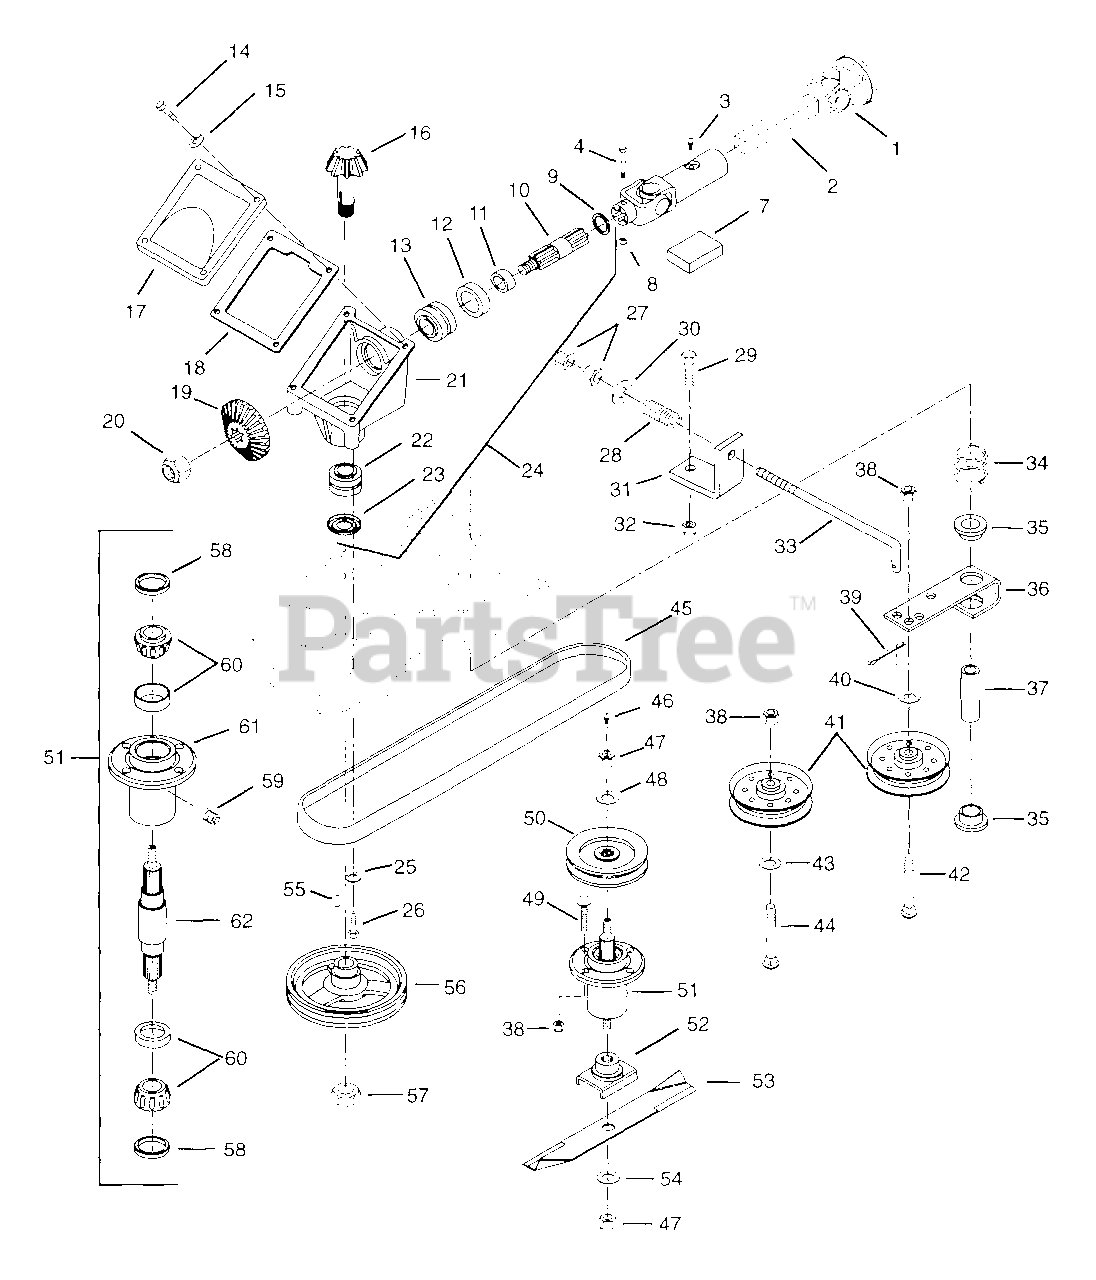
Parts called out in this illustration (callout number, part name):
1	Yoke, Quick Disconnect
2	Shaft, Prop Square Bar
3	Fitting-Lube .25-28 x .256
4	Bolt-Hex .25-20 x 2.00 Grade 5
5	Joint, U, Female End
7	Kit, Repair U-Joint
8	Nut-Locking-Nylon .250-20 Grade 2
9	Ring-Retaining 1.106 x .95
10	Shaft
11	Bushing Flange 1.00 x 1.25 x 1.25
12	Seal 1.250 x 1.983 x .250
13	Bearing-Assembly 1.000 x 1.980 x 1.243
14	Bolt-Hex .25-20 x .50 Grade 5
15	Washer Lock .250 Reg.
16	Shaft, Pinion Gear
17	Cover, Gear Housing
18	Gasket, Gear Housing
19	Gear, Bevel
20	Nut-Locking-Nylon .75-10 Grade 2
21	Casting, Gear Box
22	Bearing-Assembly .75 x 1.781 x 1.499
23	Seal 1.250 x 1.691 x .310
24	Assembly, Drive 50" Mower
25	Washer-Lock .50 Reg.
26	Bolt-Hex .50-13 x 1 Grade 5
27	Nut-Hex .375-24 Grade 2
28	Spring-Compression .125 x .78 x 1.00
29	Bolt-Hex .50-13 x 1.375
30	Washer-Flat-Steel .406 x .812 x .065
31	Support, Spring
32	Nut-Locking-Nylon .50-13 Grade 5
33	Rod, Idler 50 In. Mower
34	Spring-Compression .085 x .80 x 1.00
35	Bushing-Flange .762 x 1.0 x .580 x 1.48
36	Arm, Idler Pivot
37	Spacer .560 x .750 x 2.437
38	Nut-Locking-Nylon .375-16 Grade 2
39	Pin-Cotter .09 x 1.0
40	Bushing .406 x .750 x .188
41	Pulley-Idler 4.50 x .380
42	Bolt-Hex.38-16 x 3.00 Grade 5
43	Washer-Flat-Steel .438 x 1.000 x .083
44	Bolt-Round Head Square Neck .38-16 x 1.75
45	Belt, V .5 x .312 x 126.3
46	Fitting-Lube 1/8 (Left and Right Spindle)
47	Nut-Locking-Nylon .625-11 Grade 2
48	Washer-Flat-Steel .687 x 1.312 x .150
49	Bolt-Round Head Square Neck .38-16 x 1.25
50	Sheave
51	Service Kit Spindle Assembly
52	Weldment, Blade Cradle
53	Blade
54	Washer-Flat-Steel .656 x 1.312 x .095
55	Key-Woodruff .19 x .63
56	Sheave, 1/2 x 6.50
57	Nut-Hex-Jam .750-10
58	Seal 1.987 x 1.375 x .313
59	Relief Fitting
60	Assembly, Bearing Cup & Cone
61	Bearing Housing
62	Shaft, Spindle
